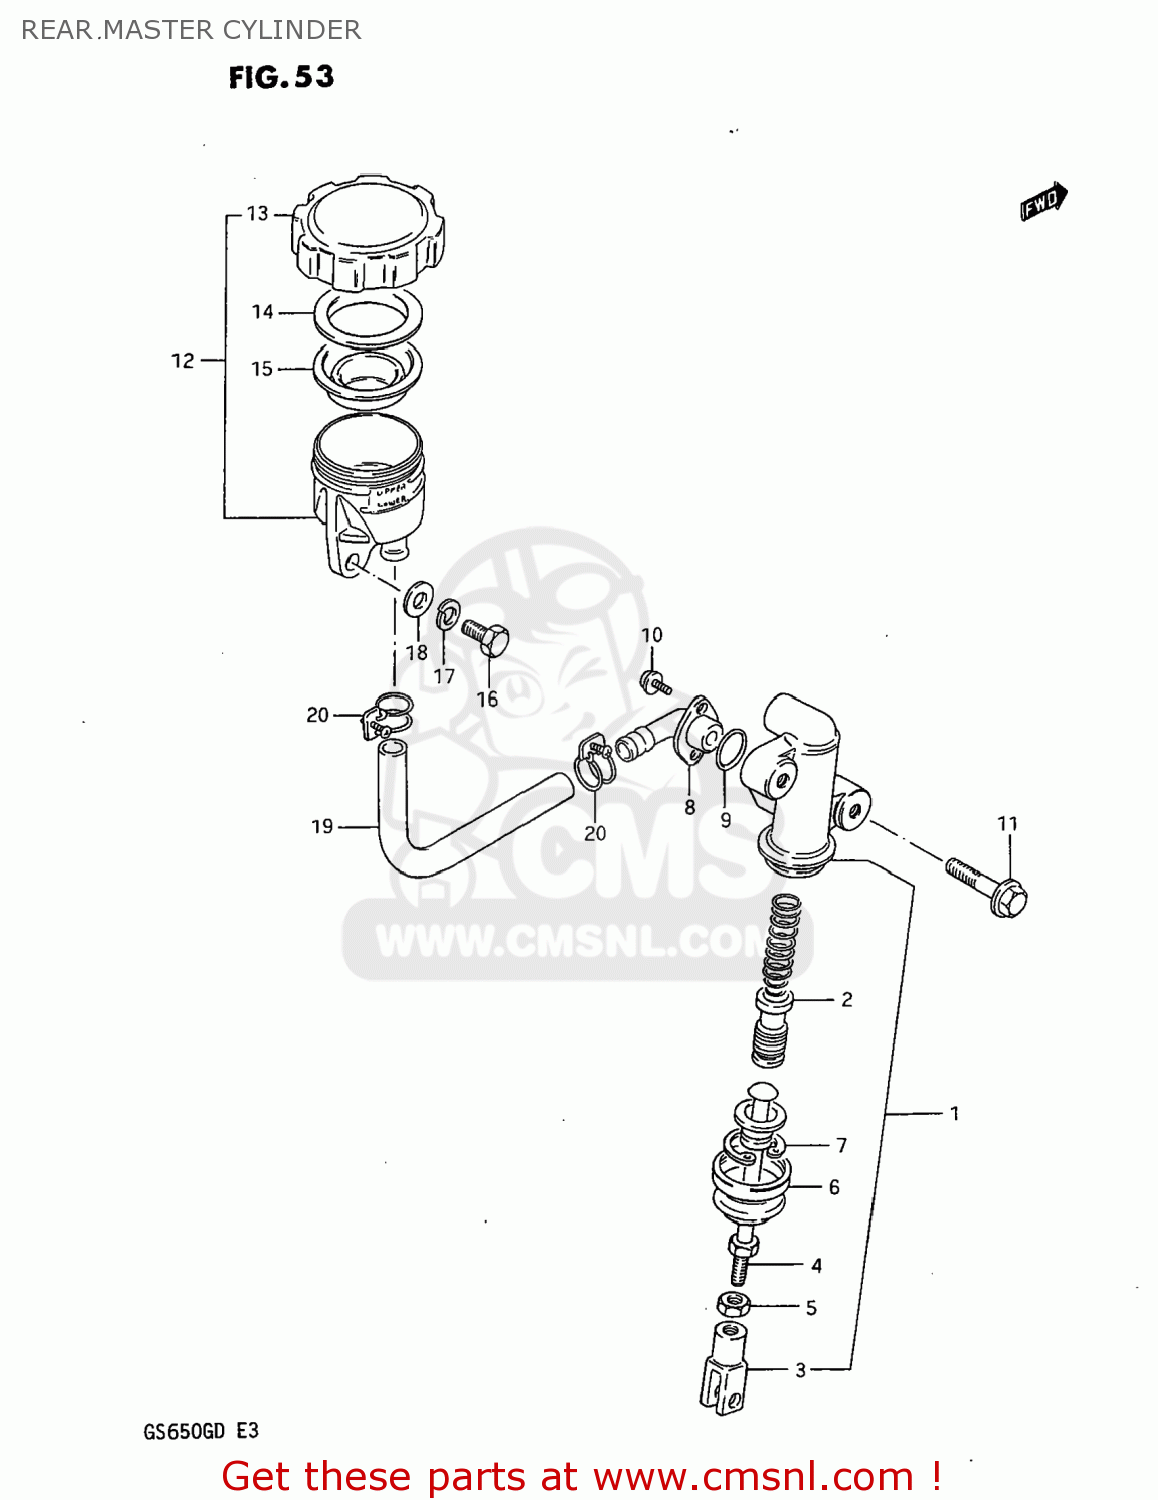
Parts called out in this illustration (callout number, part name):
1	CYLINDER ASSEMBLY,REAR MASTER
2	PISTON/CUP SET
3	YOKE
4	ROD,REAR MASTER CYLINDER
5	NUT,MASTER CYLINDER
6	BOOT
7	CIRCLIP
8	CONNECTOR,HOSE
9	O RING
10	SCREW
11	BOLT
12	TANK ASSEMBLY,RESERVOIR
13	CAP
14	PLATE,DIAPHRAGM
15	DIAPHRAGM
16	BOLT, UPPER
17	LOCK WASHER
18	WASHER
19	HOSE,RESERVOIR TANK
20	CLAMP
